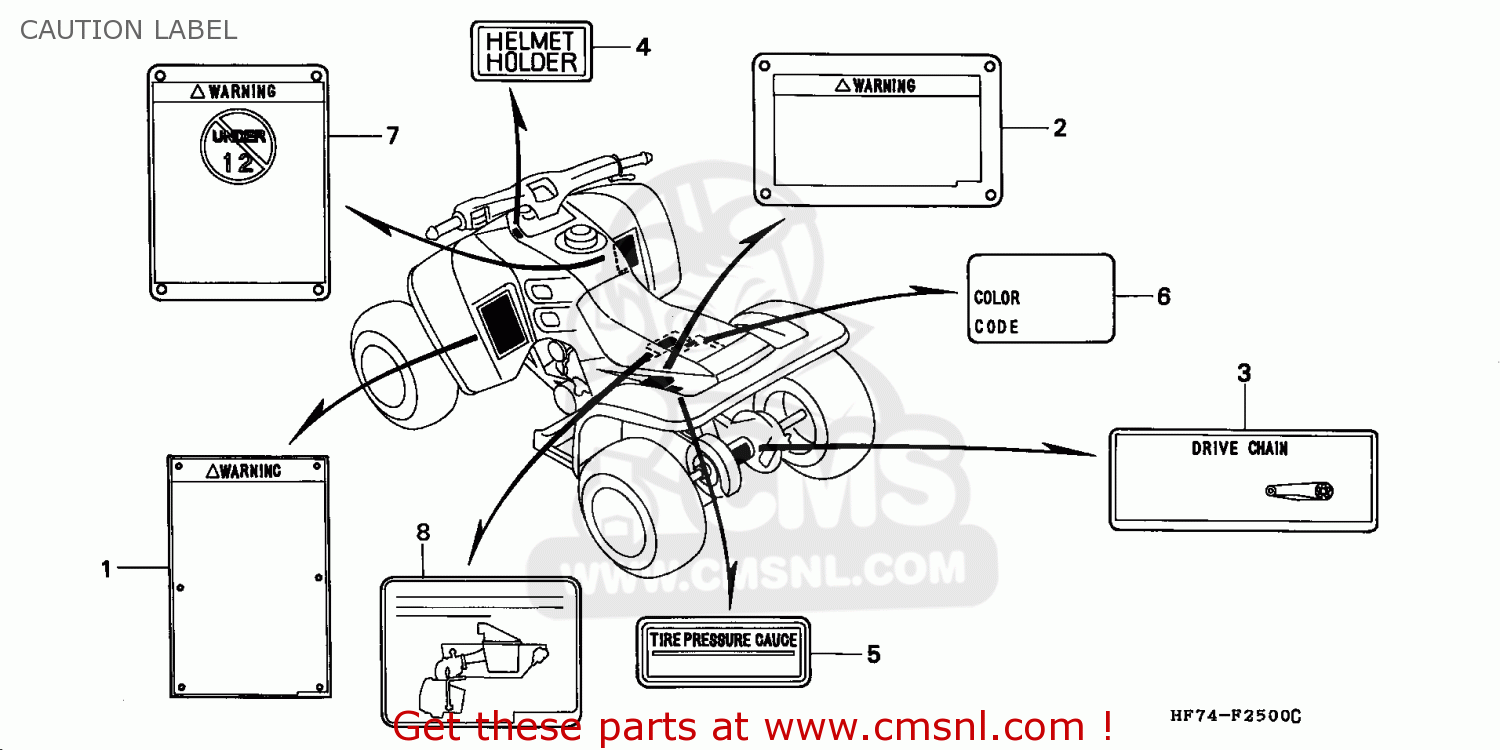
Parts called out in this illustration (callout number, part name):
1	LABEL GENERAL WAR
2	LABEL,TIRE & OVER
3	LABEL DRIVE CHAIN
4	LABEL,HELMET HOLD
5	LABEL,OWNERS MAN
7	LABEL,AGE RECOM.W
